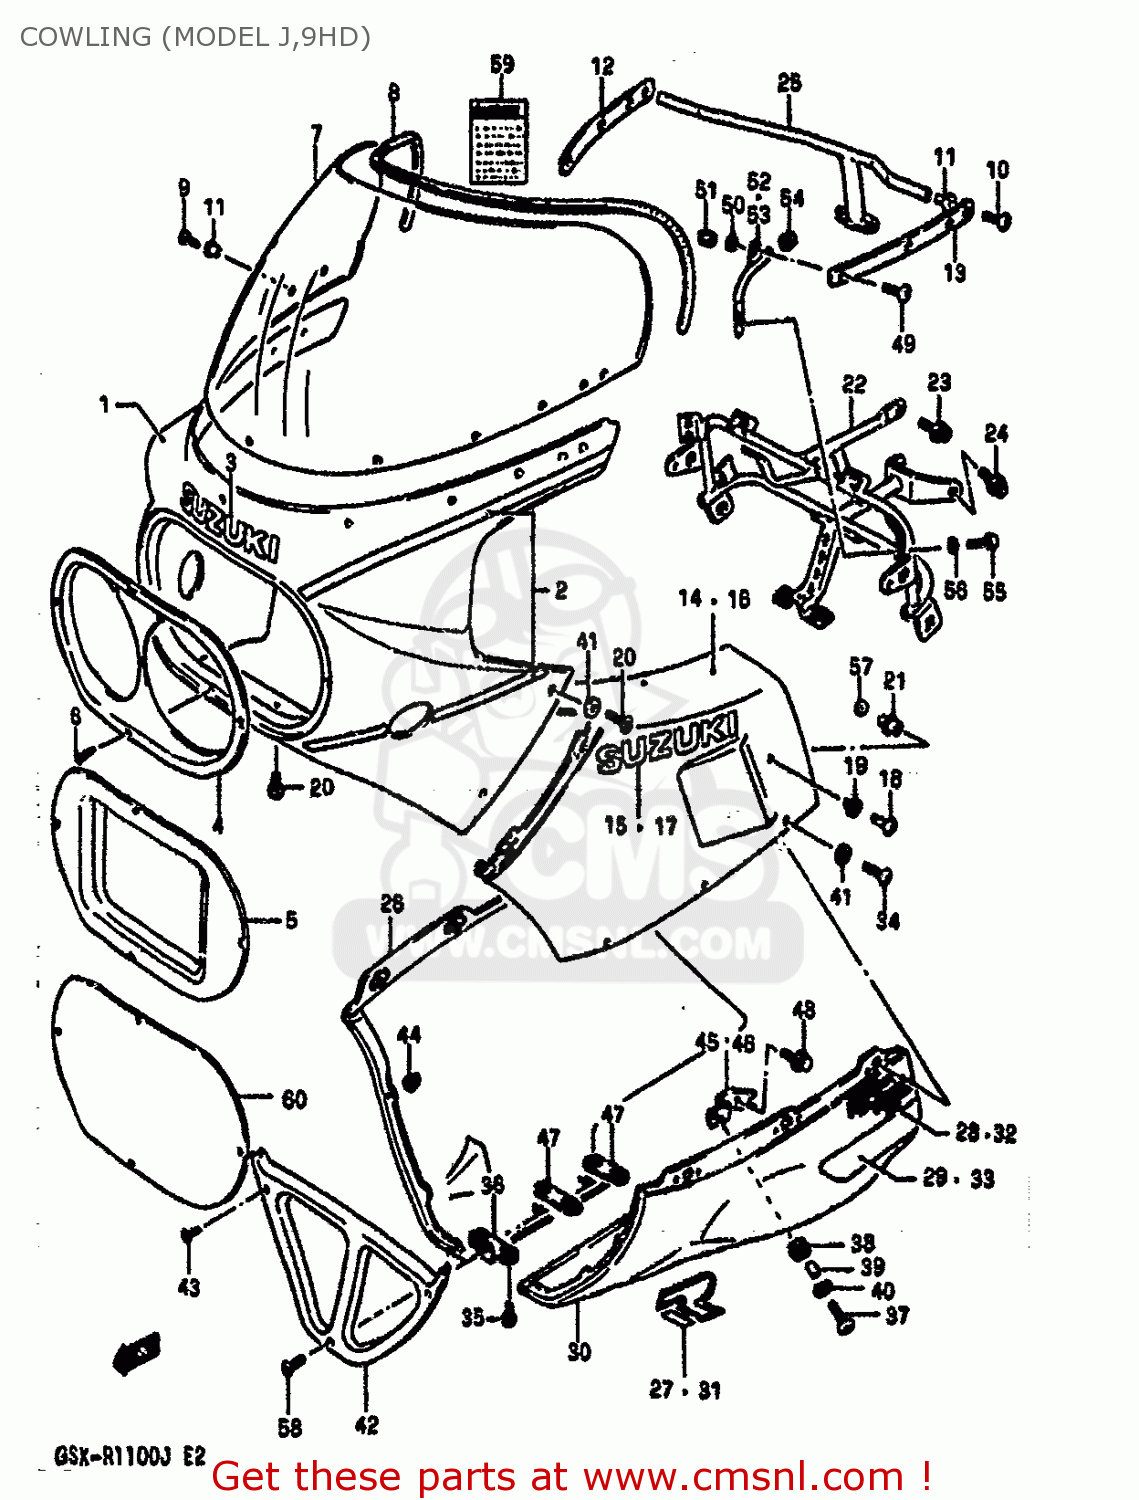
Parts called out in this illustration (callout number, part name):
1	BODY ASSEMBLY,COWLING
2	TAPE SET,COWLING,UPPER
3	EMBLEM,COWLING,UPPER (W)
4	COVER,COWLING,FRONT
5	COVER,FRONT (BLACK)
6	SCREW
7	WINDSCREEN
8	MOLDING
9	SCREW(5X14)
10	SCREW(5X18)
11	NUT,COWLING SCREEN
12	PLATE,RR VIEW MIRROR,R
13	PLATE,RR VIEW MIRROR,L
14	COVER,SIDE RH (BLACK/RED)
15	EMBLEM
16	COVER,SIDE LH (BLACK/RED)
17	EMBLEM
18	SCREW(6X12)
19	WASHER
20	SCREW(6X16)
21	CUSHION,COWLING
22	BRACE,COWLING FR
23	BOLT
24	BOLT
25	BRACE,COWLING BODY RR
26	COVER COMP,COWLING,LOWER
27	EMBLEM,COWLING,UNDER
28	EMBLEM
29	TAPE,COWLING
30	COVER COMP,COWLING,LOWER
31	EMBLEM,COWLING,UNDER
32	EMBLEM,COWLING,UNDER
33	TAPE
34	SCREW(6X16)
35	SCREW(6X16)
36	BRACE,COWLING LWR COVER
37	SCREW(6X20)
38	CUSHION
39	SPACER
40	WASHER(6.5X18X1)
41	WASHER
42	COVER,COWLING,LOWER,FRONT
43	SCREW(5X14)
44	NUT
45	BRACE,COWLING LWR,R
46	BRACE,COWLING LWR,L
47	BRACE,COWLING LWR COVER RR
48	BOLT
49	SCREW(6X16)
50	WASHER,LOCK
51	NUT 6MM
52	BRACE,MIRROR,R
53	BRACE,MIRROR,L
54	PLUG(OD:12)
55	BOLT 6X16
56	WASHER,LOCK
57	WASHER
58	SCREW(6X16)
59	LABEL (WARNING SCREEN)
60	COVER,HEADLAMP
